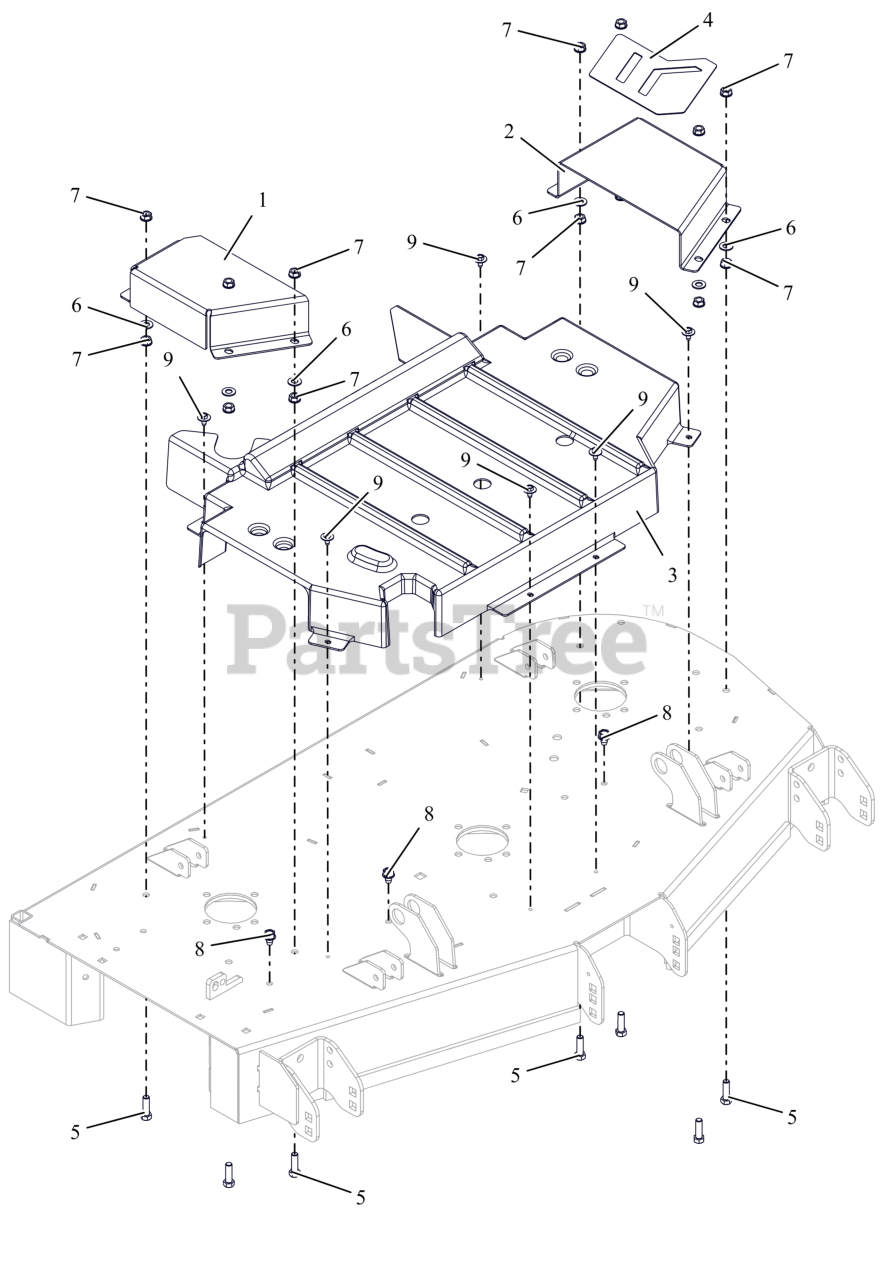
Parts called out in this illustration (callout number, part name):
1	GUARD BELT, 48" RIGHT CE
2	GUARD BELT 48" LEFT CE
3	GUARD, CENTER DECK SPINDLE CE
4	GRIP TAPE 48 BELT COVER
5	BLT, HEX .38-16X1.25 G5 ZCC
6	WSHR,FLT .406X.812X.065 ZCC
7	NUT, SPNLK-FLG .38-16 G5 ZCC
8	SCR,TAP .375-16X.50 HWH TR ZCC
9	SCR, TAP .25-20X.50 LG HWH ZCC
